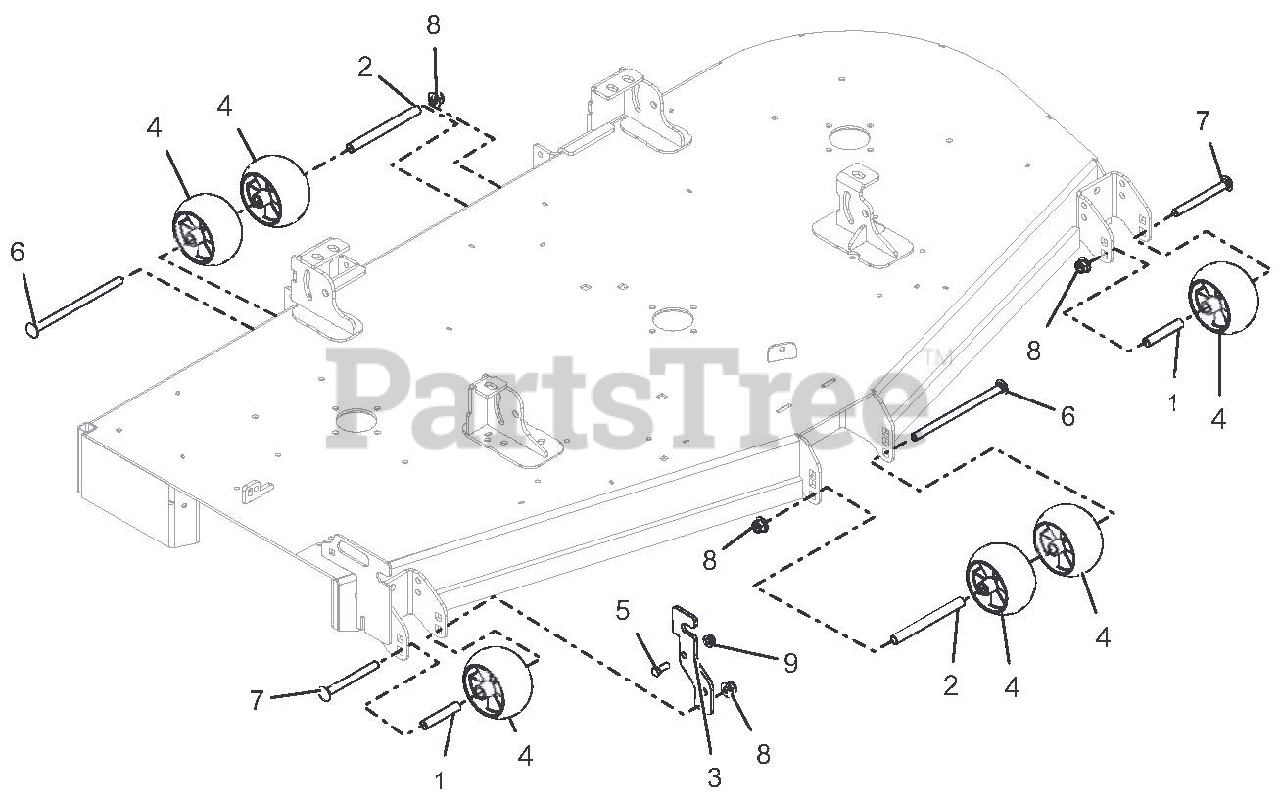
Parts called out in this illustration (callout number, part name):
1	SPACER, .510X.625X3.35
2	SPACER, .510 X .625 X 6.50
3	CHUTE STORAGE BRACKET
4	ANTI-SCALP WHEEL - 5 X 3 CTR
5	BLT-HEX .38-16X1.00 GR5 YWZC
6	BLT-RDHDSQNK .50-13X8.50 Y
7	BLT-RDHDSQNK .50-13X5.00 G5 YWZC
8	NUT-LK-NYL-FLG .50-13 YWZC
9	NUT-LK-NYL-FLG .38-16 YWZC
